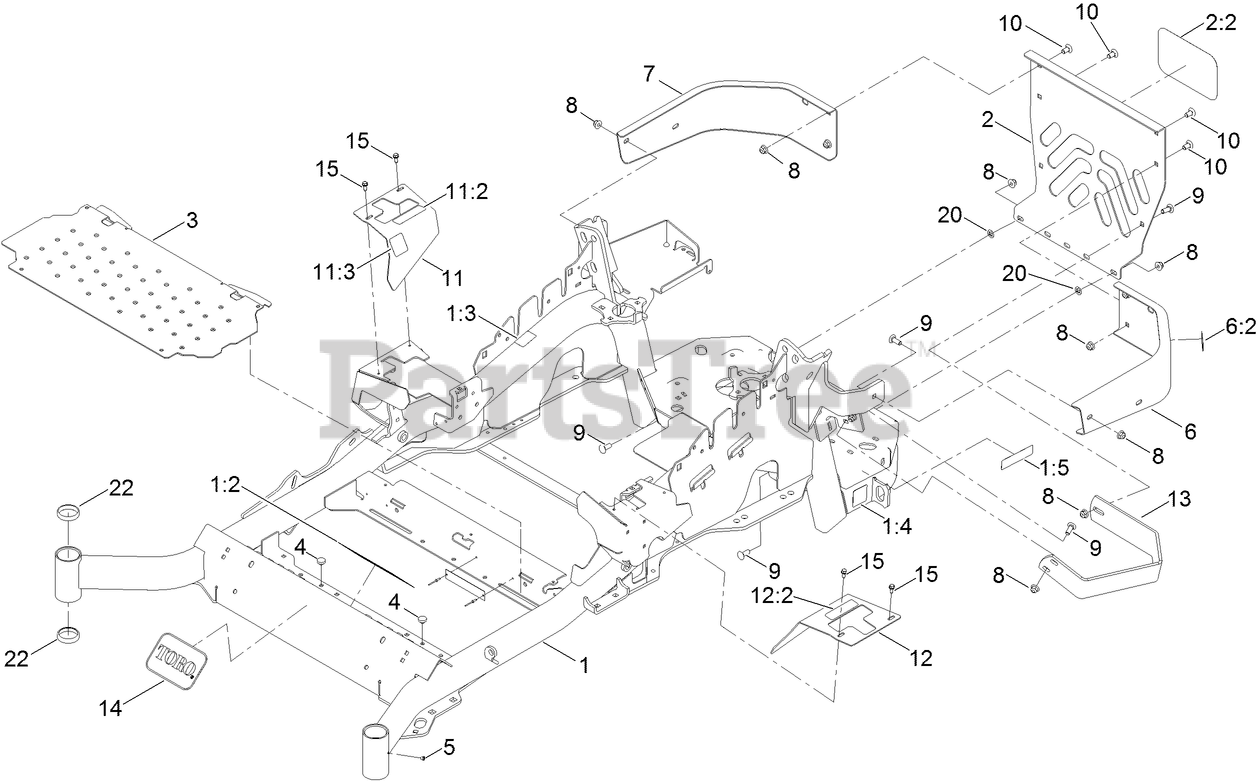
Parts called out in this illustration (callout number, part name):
1	MAINFRAME ASM
1:2	DECAL-DANGER
1:3	DECAL-WARNING
1:4	DECAL-HAZARD, PINCHED FINGER
1:5	DECAL-ARRESTOR, SPARK
2	REAR GUARD ASM
2:2	DECAL
3	FLOORPAN
4	BUMPER
6	LH BUMPER ASM
6:2	DECAL-WARNING
7	BUMPER-RH
8	NUT-HF, NI
9	SCREW-CARR
10	SCREW-CARR
11	RH MOTION CONTROL COVER ASM
11:2	DECAL-CONTROL, MOTION
11:3	DECAL-PARK BRAKE, CE
12	LH MOTION CONTROL COVER ASM
12:2	DECAL-CONTROL, MOTION
13	GUARD-MUFFLER
14	DECAL
15	SCREW-HWH
20	NUT-PUSH
22	CUP-BEARING
